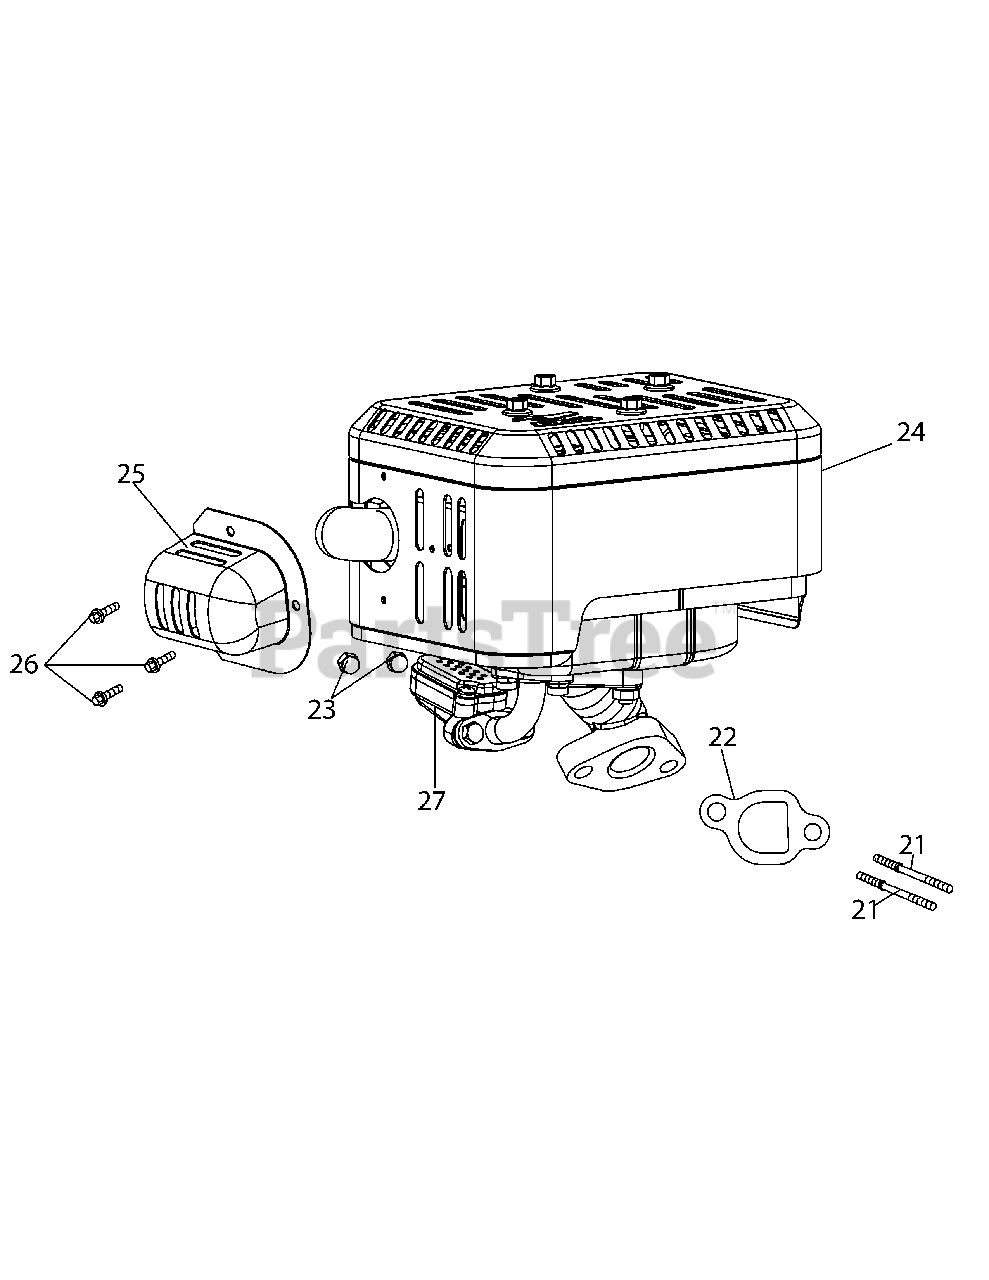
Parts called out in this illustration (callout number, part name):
21	Stud M8×38
22	Exhaust Pipe Gasket
24	Muffler Assembly
25	Exhaust Pipe Shield
27	Secondary Air Valve
